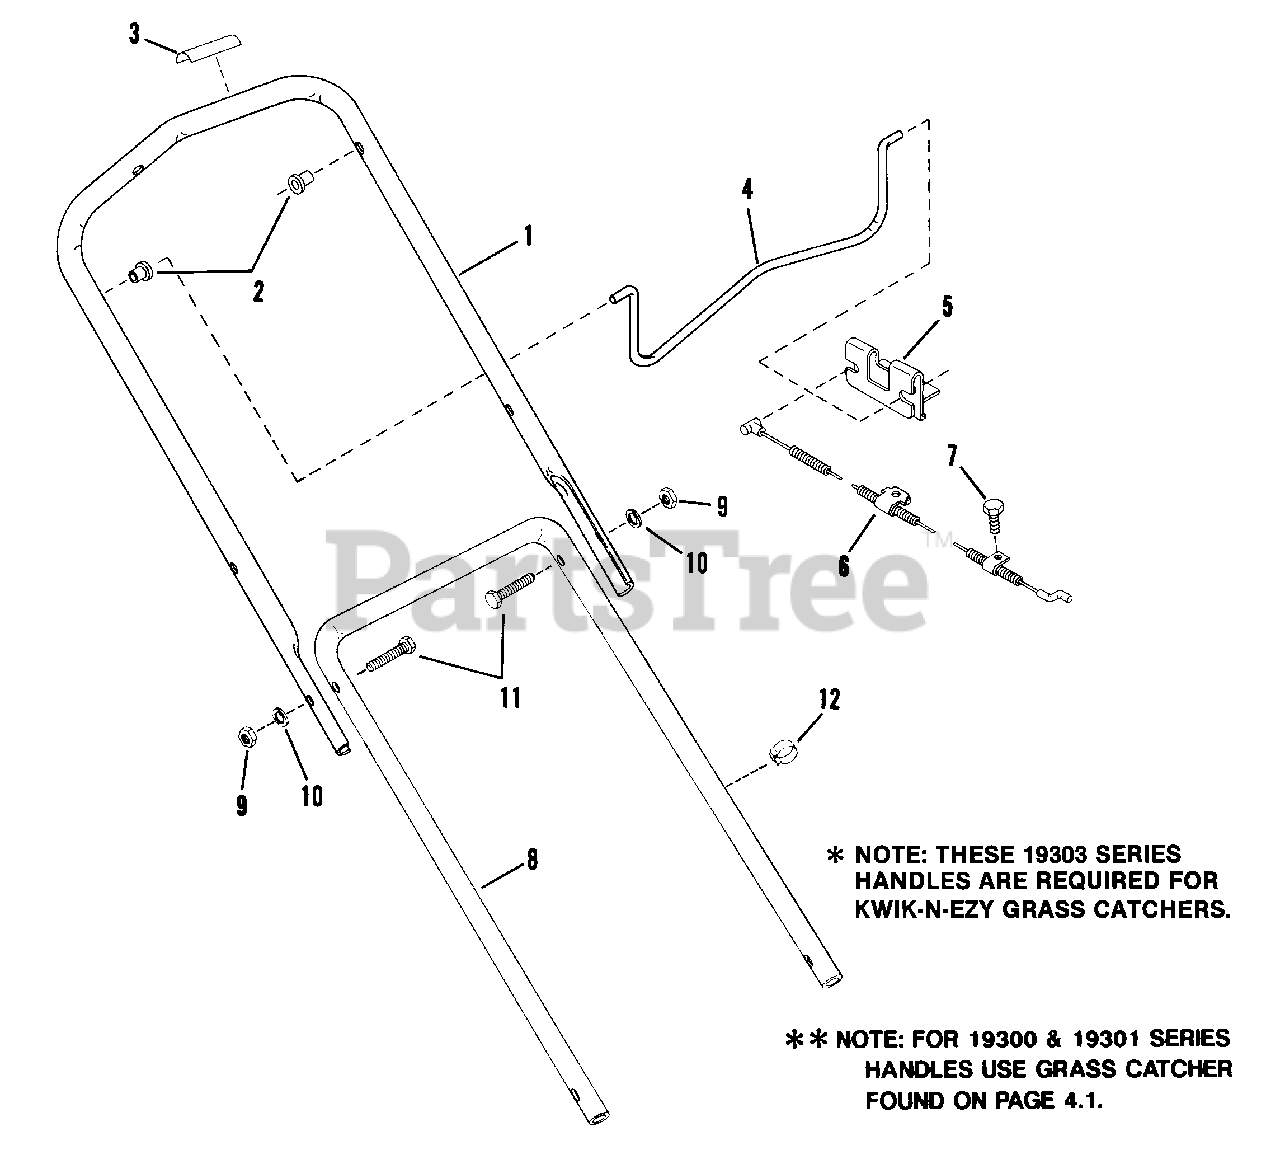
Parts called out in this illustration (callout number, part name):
1	HANDLE, Upper
2	BUSHING
3	DECAL, Blade Controls
4	CONTROL, Blade
5	CLIP (Left Hand-Tecumseh, Right Hand-Briggs)
6	CABLE, Control (Briggs)
7	SCREW, #10-32 x 1/4" Hex Sems (Tecumseh)
8	HANDLE, Middle
9	NUT, 1/4-28 Hex
10	WASHER, 1/4" Internal Tooth Lock
11	SCREW, 1/4-28 x 1-1/4" Hex Head Cap, Grade 5
12	CLIP
